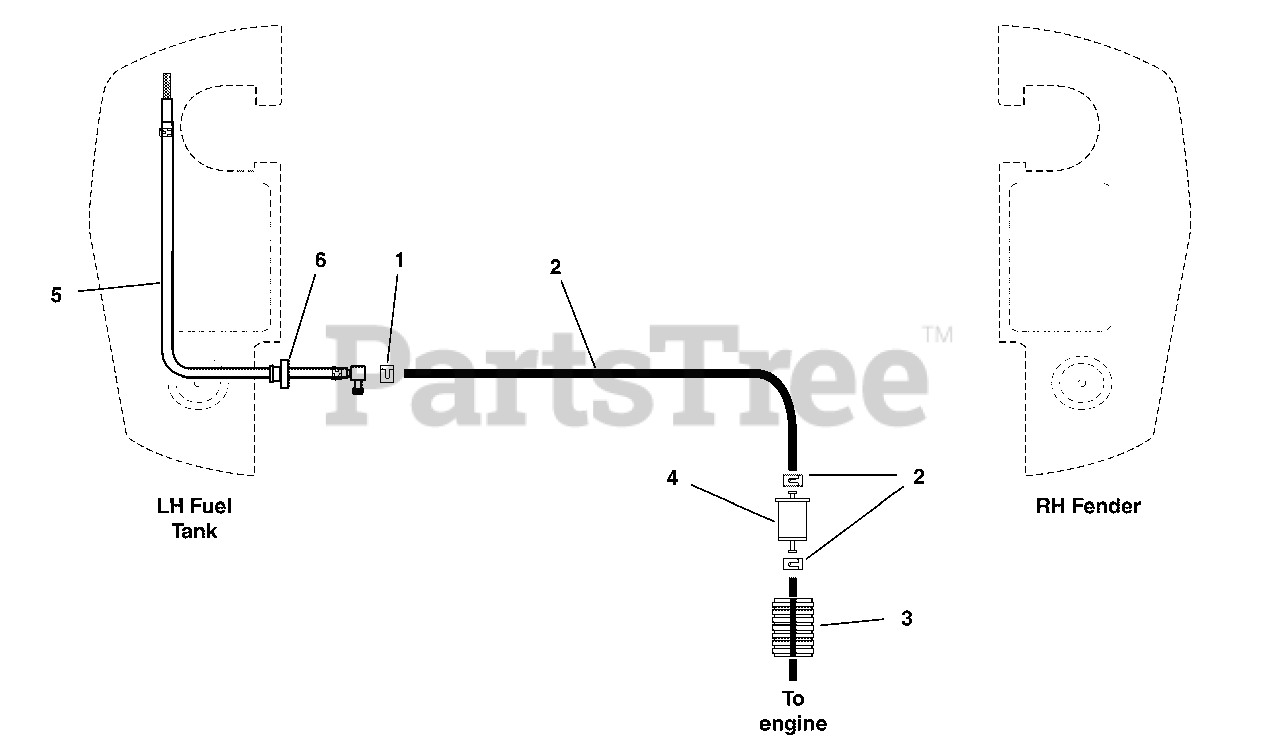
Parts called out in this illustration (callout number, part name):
1	CLAMP, HOSE, EXTERNAL, 1/2 - RED
2	HOSE, FUEL, 1/4 IN, LW PRMTN
3	WIRE LOOM, 1/2 ID, 13.00 LONG
4	FUEL FILTER (SV)
5	HOSE ASSEMBLY
6	BUSHING
